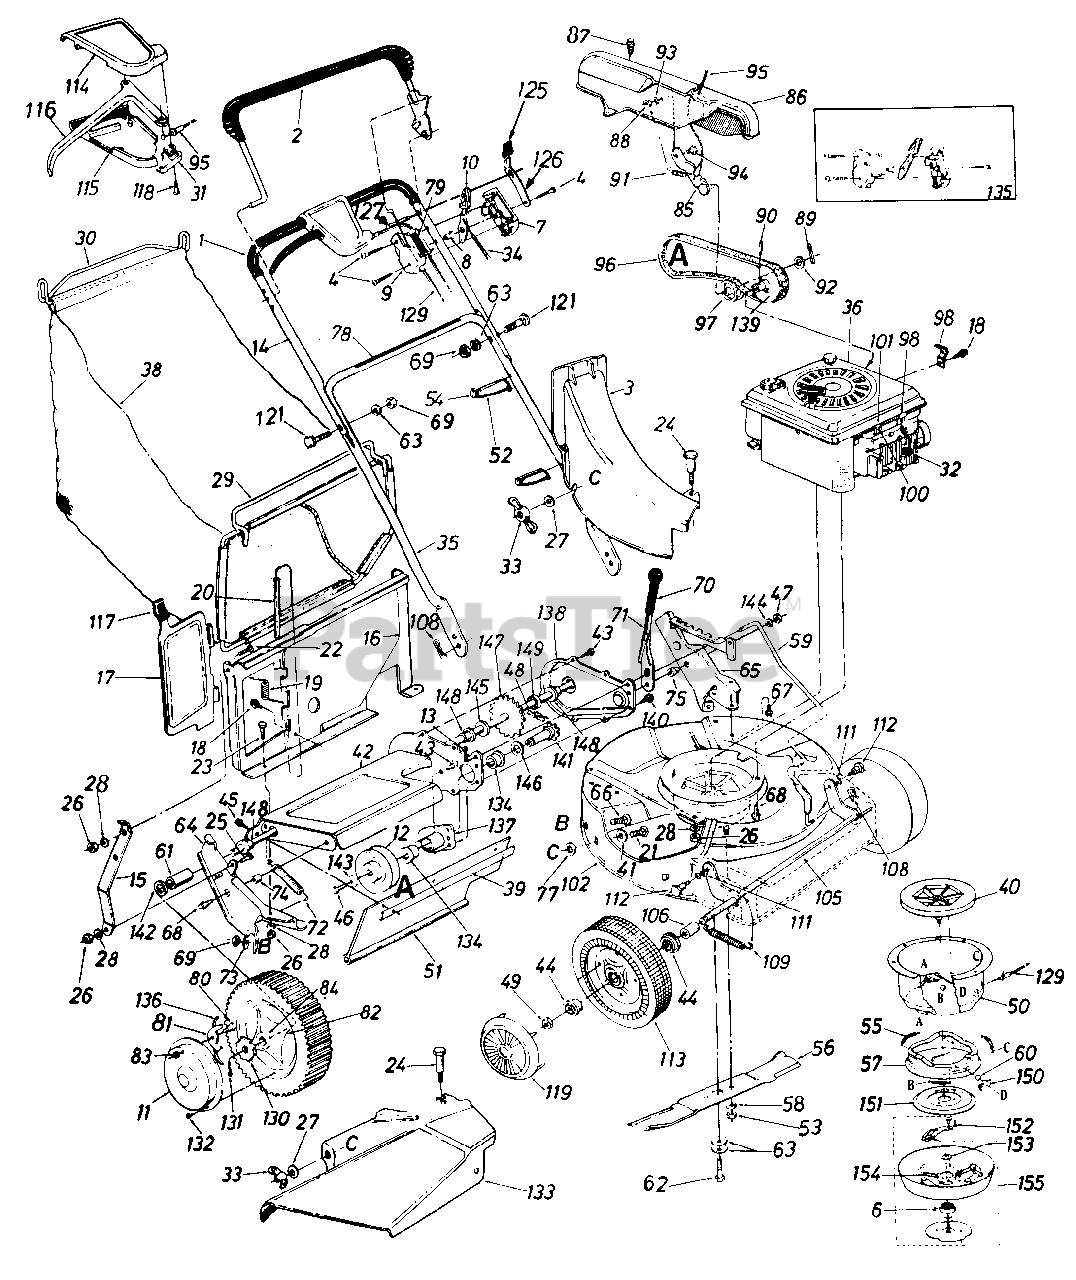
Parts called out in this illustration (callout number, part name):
1	Grip
2	Control Handle Ass'y. L.H.
3	Top Discharge Chute Ass'y.
4	Truss Mach. Scr. #12 x 1.50" Lg.
6	Ball Brg. .669" I.D. x 1.574"
7	Control Panel Half
8	Control Disc Pin
9	Clutch Panel Half
10	Throttle Control Lever
11	Hub Cap
12	1/2" V-Pulley
13	Cotter Pin 8/32" Dia. x .75"*
14	Upper Handle Chrome
15	Panel Support Brkt.
16	Top Catcher Panel
17	Top Door
18	Hex B-Tap Scr. #10 x .38"
19	Torsion Spring
21	Carriage Bolt 1/4-20 x .62"*
22	Truss Mach . Scr. 1/4-20 x-1/2" Lg.
23	Hex Bolt 1/4-20 x .50" Lg.*
24	Shoulder Bolt .312 Dia. x .18 Lg. Special
25	Hex Bolt 1/4-20 x .62" Lg.*
26	Hex Nut 1/4-20 Thd.*
27	Fl-Wash. .280" I.D. x .620"
28	L-Wash. 1/4" I.D.*
29	Front Grass Catcher Frame
30	Grass Catcher Handle
31	S.P. Control Cover
32	Spark Plug Insulator
34	Throttle Control Wire 58"
35	Lower Handle Chrome
36	Engine
38	21" Top Discharge Grass Bag
39	Retaining Strip
41	Fl-Wash. .344" I.D. x .62"
42	Chain Axle Ass'y.
43	Hex B-Tap Scr. 1/4" x .38" Lg.
44	Flange Ball Bearing 1/2" I.D.
45	Hex AB-Tap Scr. 1/4 x .62"
46	Hex Wash. TT-Tap Scr. 1/4-20
47	Hex Patch L-Nut 3/8-24 Thd.
48	#48 Chain .500" Pitch x .30 Links
49	Hex L-Nut 1/2-20 Thd.
50	Clutch Housing
51	Rear Flap 3.75" x 17.30" Lg.
53	Hex Nut 3/8-24 Thd.
54	Cable Anchor
55	Extension Spring .35" O.D. x 1.75" Lg.
57	Brake Cup Cone
58	L-Wash. 3/8" I.D.*
59	Height Adj. Rod 19.42" Lg.
60	Steel Ball .500" Dia.
61	Spacer .51" I.D. x .69" O.D. x.69" Lg.
62	Hex Cent. L-Bolt 3/8-24 x 2.0" Lg. (Grade 8)
63	Bell-Wash. 3/8" I.D.
64	R.H. Handle Wheel Brkt. Ass'y.
65	L.H. Handle Wheel Brkt. Ass'y.
66	Carriage Bolt 5/16-18 x .62"*
67	Hex Wash. Hd. B-Tap Scr. 5/16-18
68	Hex Wash. Hd. TT-Tap Scr. 3/8-16
69	Hex Nut 5/16-18 Thd.*
71	Height Adj. Lever
72	Extension Spring .50" O.D. x 3.80" Lg.
73	Bell-Wash. .345" I.D. x .88"
74	Spacer .385" I.D. x .502" O.D. x .270" Lg.
75	Shld. Spacer .500" Dia. x .100
77	Bolt Retainer 1/4 X .50" O.D.
78	Instruction Label
79	Control Label
80	Shld. Scr. .342" Dia. x .268
81	Pawl
82	Wheel Ass'y. Comp. Rear 8 x 1.75
83	Hex Ins. L-Nut 1/4-20 Thd.
84	Flange Ball Bearing 1/2" I.D.
85	Belt Idler Bracket Ass'y.
86	Belt Cover
87	Hex Wash. S-Tap Scr. 1/4-20 x.50" Lg.
88	Hex Nut 1/4-20 Thd.*
89	Cotter Pin 1/8" Dia. x 1.00" Lg. *
90	Spring Pin Spir. 3/16" Dia. x 1.00" Lg.
91	Extension Spring .33" O.D. x 1.12" Lg.
92	Fl-Wash. .531" I.D. x .930" O.D. x .050
93	L-Wash. 1/4" I.D.*
94	Shld. Bolt .375" Dia. x .181
95	S.P. Cable x 53.0" Lg.
96	"V"-Belt 1/2 " X 32.0" Lg.
97	Fl-Idler Plastic 1.62" Dia. (Grade 8)
98	Casing Clamp
100	Hex B-Tap Scr. #10 x .62"
101	Casing Clamp
106	Sleeve .526" I.D. x .690" O.D. x .880" Lg.
108	Intern. Cotter Pin 5/16" Dia.
109	Extension Spring .50" O.D. x 3.20" Lg.
111	Intern. L-Wash. 3/8 I.D.*
112	Shld. Bolt .623" Dia. x .425
113	Front-Wheel Ass'y. Comp. 7 x 1.50
114	Self-Propelled Control Cover
115	Self-Propelled Control Cover
116	Control Lever
118	Fl-"C"-Sunk Hd. Tap Scr. #10 x .75" Lg.
119	Hub Cap Plastic
121	Curved Carr. Bolt 5/16-18 x 1.38" Lg.
125	Spring Lever Knob
126	Lockout Spring
127	Lock Pin .314" Dia. x 1.75"
129	Blade Brake/Clutch Cable 46" Lg.
130	Ratchet Wheel 1.62" O.D.
131	Cotter Pin 1/8" Dia. x 1.00" Lg.*
132	Pan Hd. Tap Scr. #12 x .50" Lg.
133	Side Chute Deflector Ass'y.
134	Flange Bushing
135	Kit Control Housing Comp.
136	Spring Nylon
137	Bearing Hub Flange Ass'y.
138	Chain Cover
139	Engine Pulley 1/2"
140	Hex Wash. S-Tap Scr. 1/4-20 x.50" Lg.
141	Sprocket Shaft Ass'y.
142	Fl-Wash. .531" I.D. x .93" O.D.
143	Bell-Wash. .265" I.D. x .75" O.D.
144	Fl-Wash. .385" I.D. x .87" O.D.
145	Fl-Wash. .51" I.D. x 1.0" O.D.
146	Fl-Wash. .62" I.D. x 1.12" O.D.
147	Rear Shaft Ass'y. 22.05" Lg.
148	Hex Flange Bearing .506" I.D. Plastic
149	Spacer .510" I.D. x 1.00" O.D. x .210" Lg.
151	Clutching Cone
152	Hex Tap L-Scr. 1/4-20 x .75" Lg.
153	Fl-Wash. .690" I.D. x 1.060" O.D.
154	Compression Spring .35" O.D. x 2.00" Lg.
155	Clutch Blade Housing Ass'y.
8204-000-6	Hardware Pack
